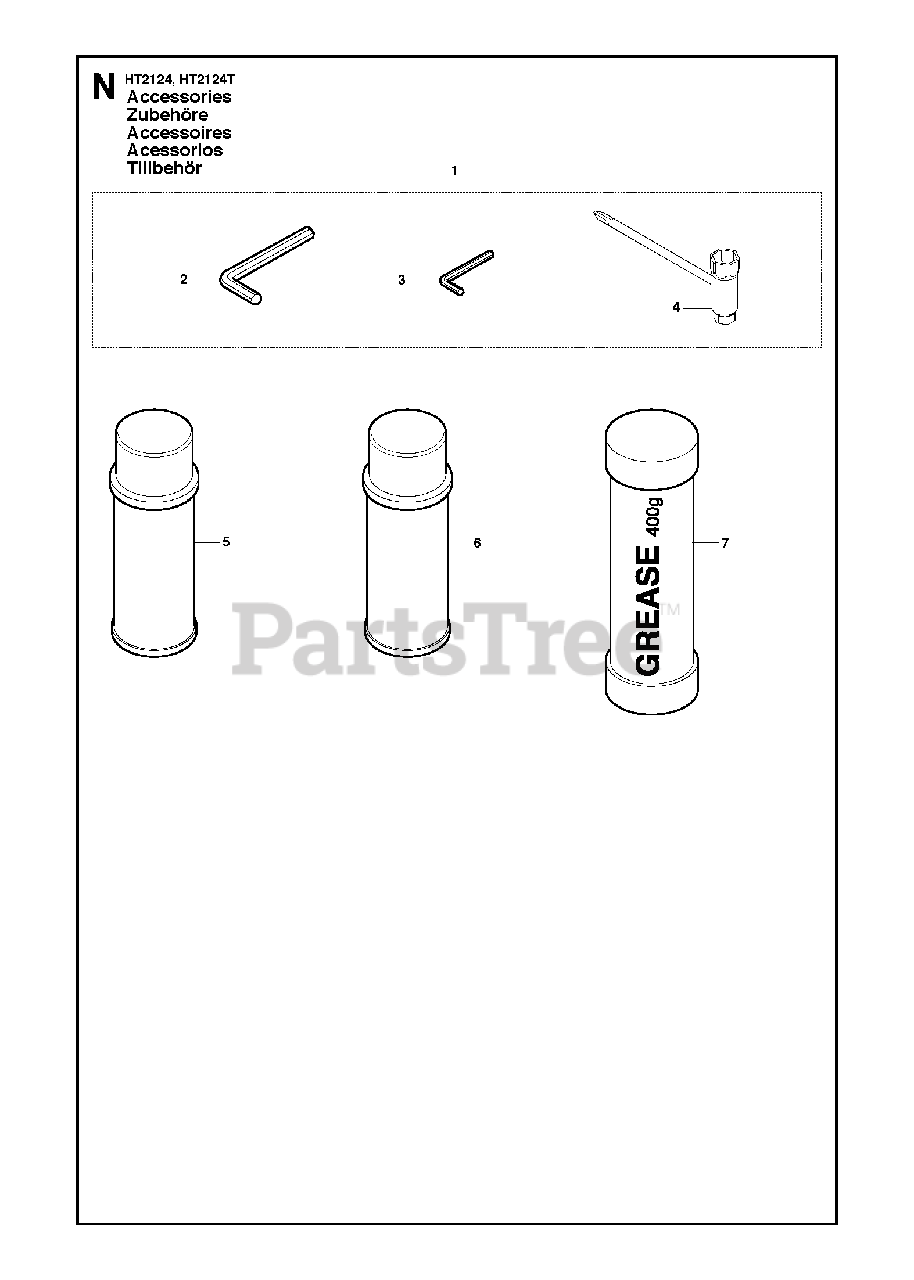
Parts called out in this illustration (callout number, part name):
2	ALLEN KEY
3	ALLEN KEY
4	COMBINATION WRENCH
5	UL 22 - 12 PACK
6	CUTTER BAR LUBE/12 PACK UL21
7	GREASE 400 GRAMS
